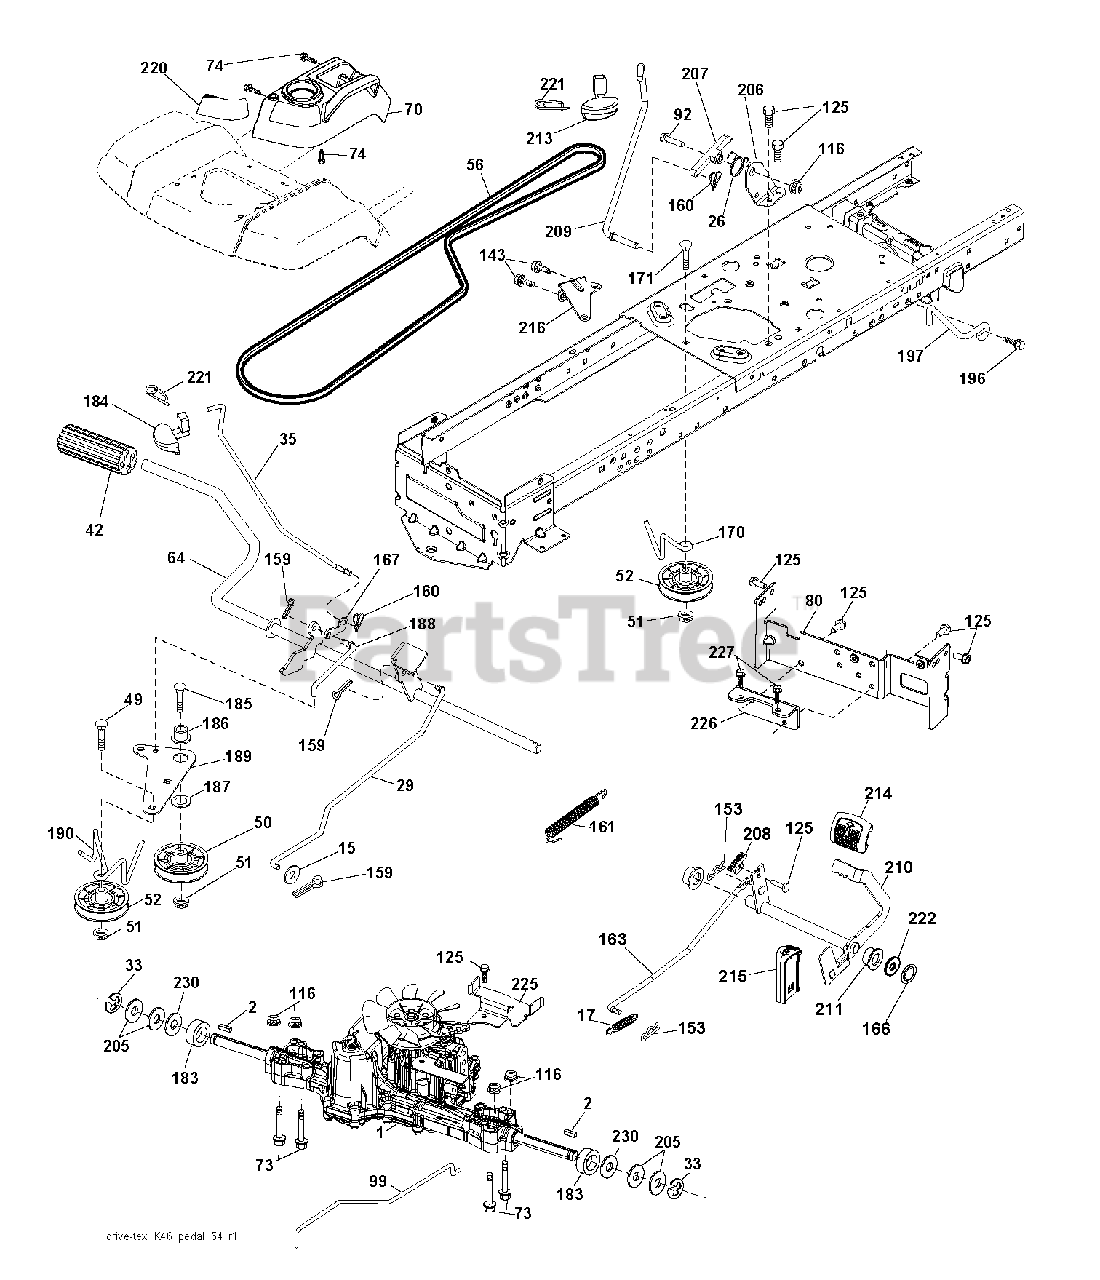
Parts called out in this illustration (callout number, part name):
2	SQUARE KEY
15	WASHER
17	SPRING.BRAKE.K46.GREEN
26	SPRING.RETURN.CRUISE
29	ROD.BRAKE.K46
35	ROD.BRAKE.PARTK.HUSQ.TEX
42	PEDAL COVER T
50	IDLER.FLAT.910.OFFSET
51	NUT LOCK FLG 3/8-16 UNC
52	IDLER.V-GROOVE.910.OFFSET
56	V-BELT.MOWER.92.40.42/K46
64	SHAFT.ASM.PEDAL.BRK.CNTR
70	CONSOLE.ASM.RH.GT.FC.HUSQ
74	SCREW.HI-LO.CONSOLE
80	STRAP.TORQUE.K46.K57R.TT
92	BOLT
99	ROD.SPRING.BYPASS.K46.LT.Z
116	NUT LOCK HEX FLANGE 5/16-18
125	SCREW
143	SCREW LT
153	RETAINER M
159	COTTER PIN
160	RETAINER CLIP
161	SPRING, RETURN LT
163	ROD.CONTROL.PEDAL.K46
166	NUT.PUSH.625
167	LATCH.BRAKE.SPRING
170	KEEPER.V-IDLER.CENTER.
183	SPACER AXLE
184	RB HANDLE.PARKG.BRK.HUS/PRED
186	SPACER.RETAINER
187	WASHER 12/32X2X10GA
188	RP LINK.CLUTCH.GROUND.DRIVE
189	BELLCRANK.GROUND.DRIVE.TEX.
190	KEEPER.BELLCRANK.DRIVE
196	SCREW 3/8-16X1
197	LINK.CLUTCH.ANIT-ROTAT
206	BRKT.MOUNT.LATCH.CRUIS
207	LATCH.CONTROL.CRUISE
208	GEAR.SECTOR.CONTROL.CR
209	ROD.CONTROL.CRUISE.GT.
210	ROCKER.ASM.PEDAL.CONTR
211	BEARING.NYLON
213	KNOB.CONTROL.CRUSIE.HU
214	PEDAL.FORWARD.PAD.TEX
215	PEDAL.REVERSE.TEX.GT.4
216	BRACKET.PULLEY.IDLER.W/TEX
220	REFLECTOR.RH.TEX GT
221	RETAINER.SPRING.CLIP.H
222	WASHER 21/32 X 1-1/4 X 10 GA.
225	KEEPER.BELT.TRANSAXLE.K46
226	BRACKET.MOUNT.TORQUE.K46.TLT
227	SCREW
230	WASHER.HARDENED
